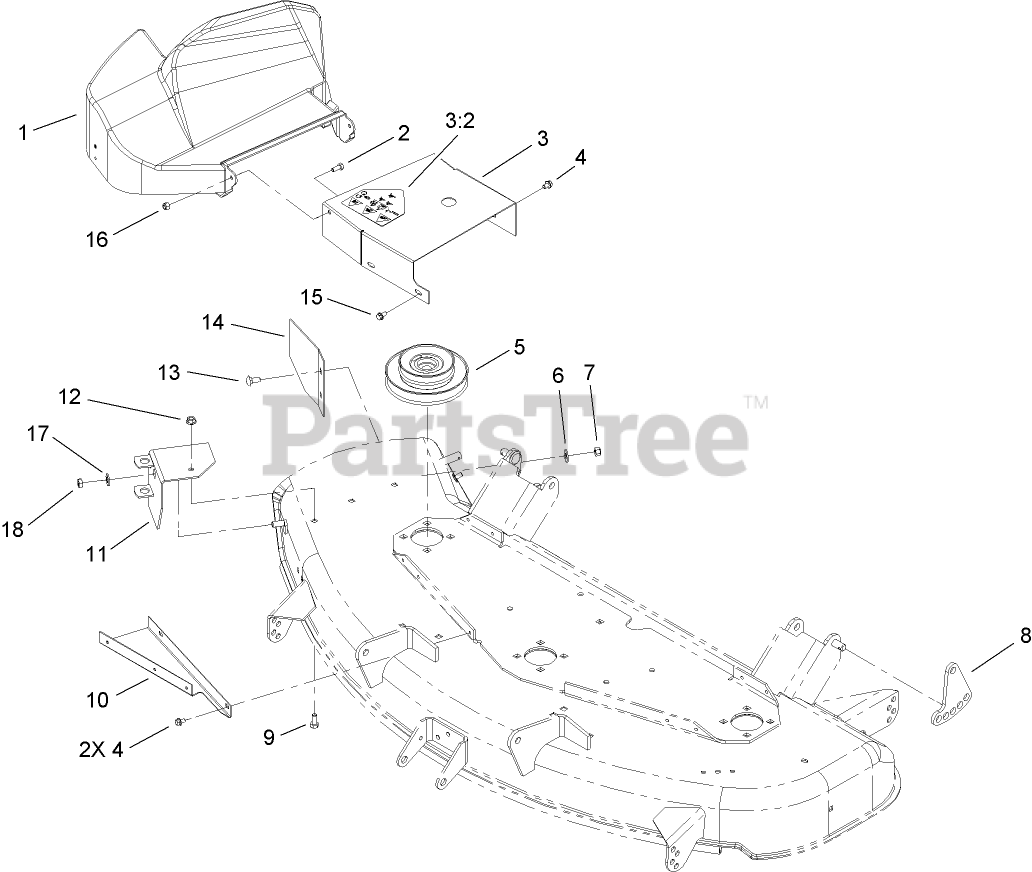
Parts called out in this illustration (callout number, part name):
1	BELT SHIELD ASM
2	SCREW-HH
3	COVER ASM
3:2	DECAL-DANGER, SHIELD
4	SCREW-HHF
5	PULLEY
6	WASHER-FLAT
7	NUT-LOCK, NI
8	LINK-HOC, ADJUSTING
9	SCREW-HH
10	ADAPTER-SHIELD
11	PIVOT BRACKET ASM
12	NUT-HF
13	BOLT-CARR
15	SCREW-HWH
16	NUT-LOCK, NI
17	WASHER-FLAT
18	NUT-HJ
